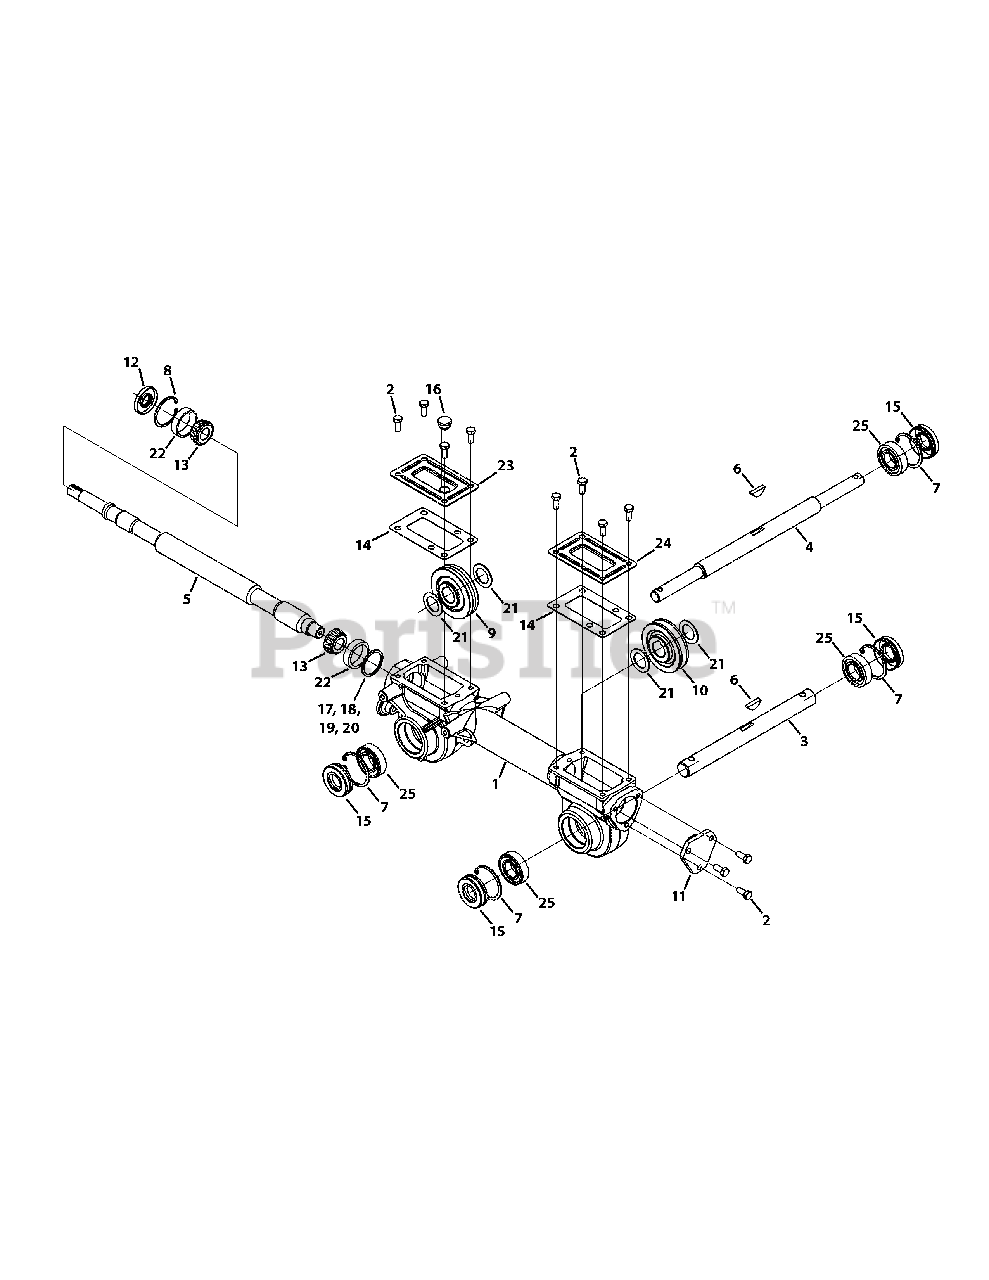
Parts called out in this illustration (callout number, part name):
1	Transmission Housing
2	Hex Head Screw, 5/16-18 x 75
3	Tiller Shaft
4	Wheel Shaft
5	CRT Drive Shaft
6	Key, 25 x 1062
7	Retainer Ring
8	Retainer Ring
9	RH Gear Worm, 61T
10	LH Gear Worm, 30T
11	Bearing Cover
12	Oil Seal, 750 SHF x 1783 BORE
13	Cone Bearing
14	Gear Housing Gasket
15	Oil Seal, 100 SHF x 200 BORE
16	Rubber Oil Plug
17	Washer, Flat, 150 x 175 x 062
18	Washer, Flat, 150 x 175 x 005
19	Washer, Flat, 150 x 175 x 03
20	Washer, Flat, 150 x 175 x 010
21	Washer, Flat, 1010 x 156 x 060
22	Cup Bearing
23	Tiller Transmission Cover
24	Tiller Transmission Cover
25	Ball Bearing, 1 x 52 x 15 x 6205-1
